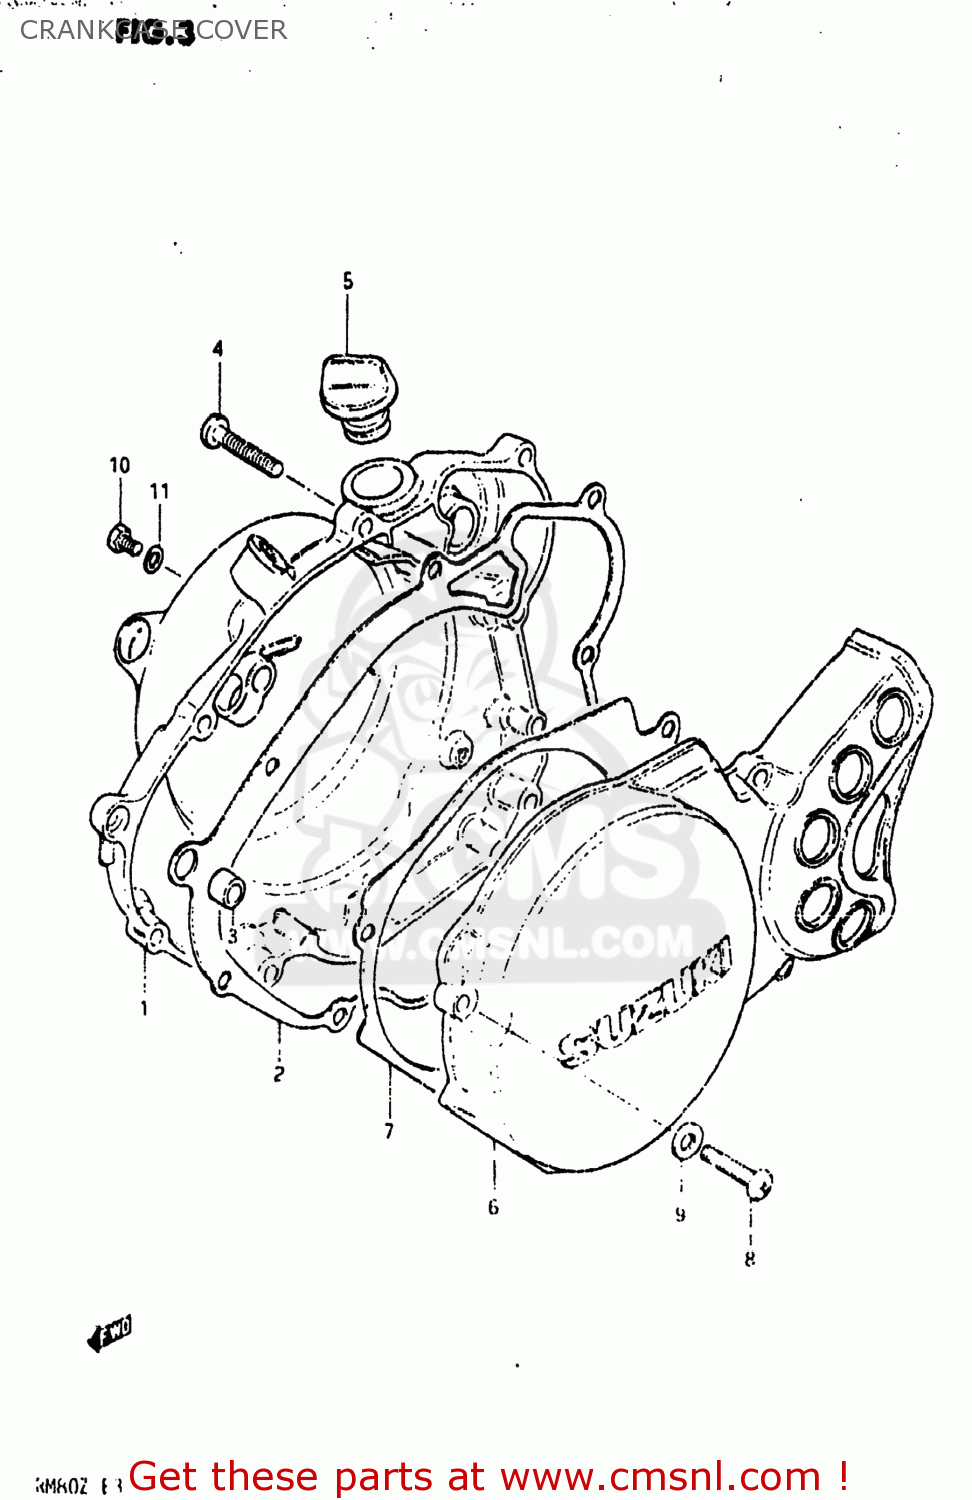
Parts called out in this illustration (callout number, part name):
1	COVER,CLUTCH
2	GASKET,CLUTCH COVER (MCA)
3	PIN
4	SCREW
5	PLUG
6	COVER
7	GASKET,MAGNETO COVER (NAS)
8	SCREW 5X20
9	WASHER
10	SCREW(6X10)
11	GASKET(6.2X11X1) (NAS)
